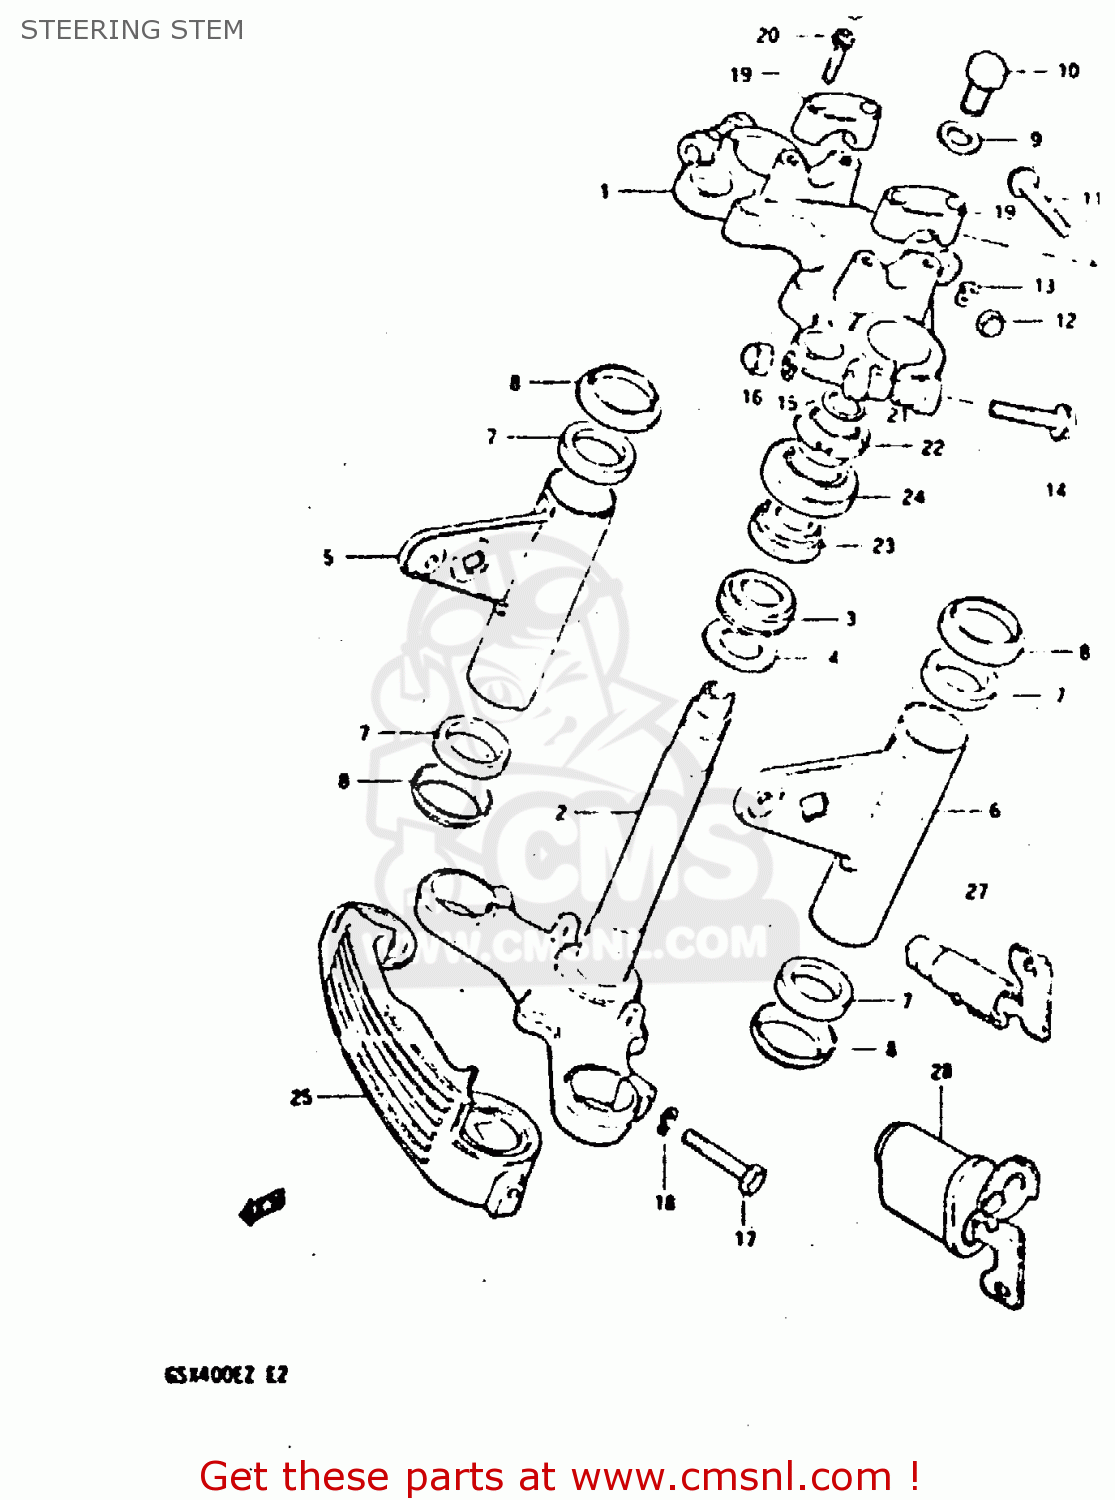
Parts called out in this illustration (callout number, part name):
1	HEAD,STEERING STEM
2	STEM,STEERING
3	BEARING
4	WASHER,THRUST
5	BRACKET,HEADLAMP,RIGHT
6	BRACKET,HEADLAMP,LEFT
7	CUSHION,HEADLAMP BRACKET
8	CAP,HEADLAMP BRACKET
9	WASHER
10	BOLT(12X20)
11	BOLT
12	NUT
13	LOCK WASHER
14	BOLT 10X55
15	LOCK WASHER
16	NUT
17	BOLT 10X40
18	LOCK WASHER
19	HOLDER,HANDLEBAR(BLACK)
20	BOLT
21	WASHER(18.5X24X1)
22	NUT,STEERING STEM
23	TAPER,ROLLER BEARING
24	DUST SEAL,STEERING UPR
25	COVER,FRONT FORK
26	CAP(OD:14.5)
